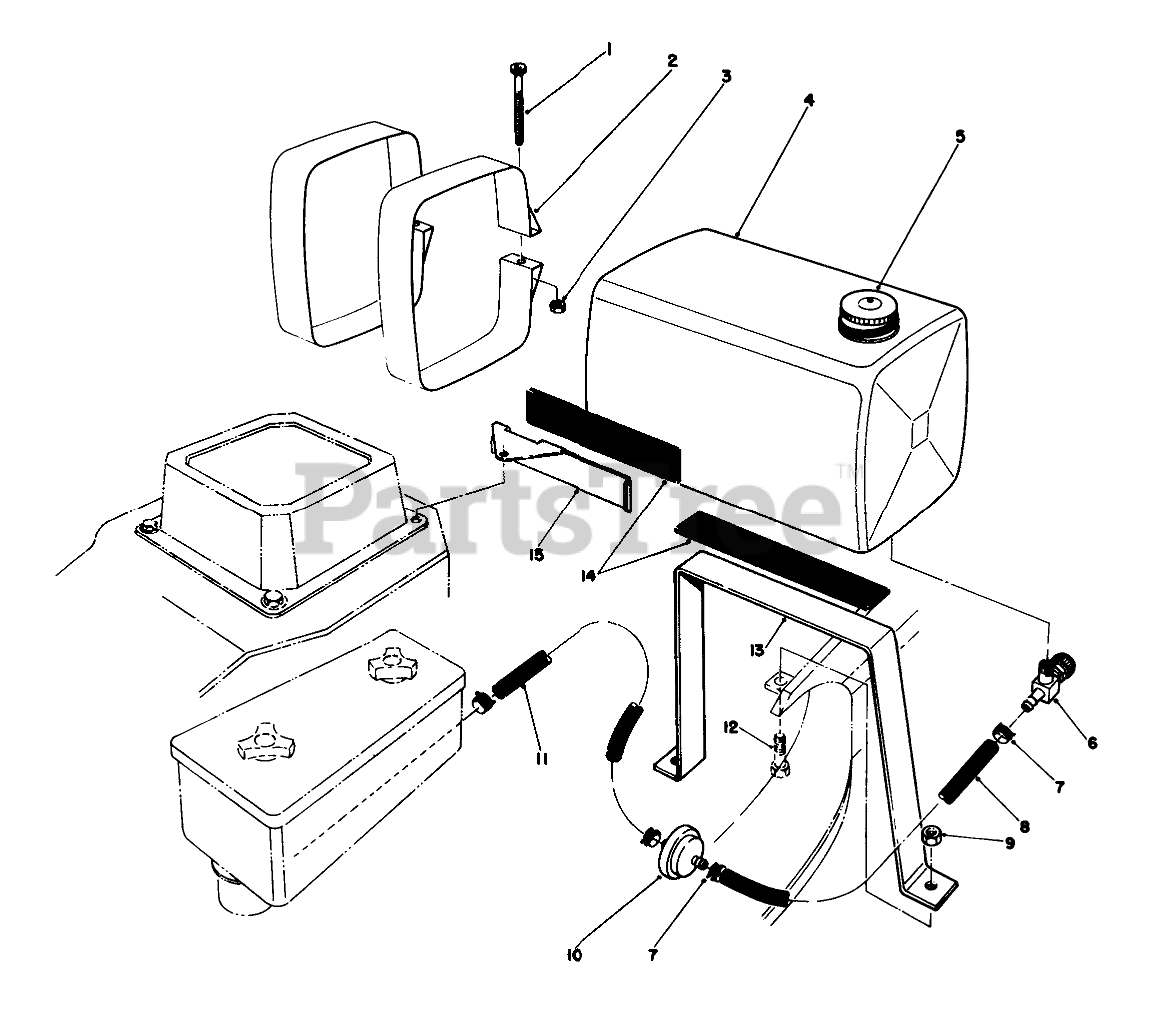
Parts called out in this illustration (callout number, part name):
1	SCREW-HSH
2	TANK MTG STRAP WA
3	NUT-HEX
4	Tank-Gas (Incl. Ref. #5)
5	CAP CAP
6	.125 ID SHUTOFF VALVE
7	CLAMP-FUEL LINE
8	LINE-GAS
9	NUT-LOCK, NI
10	FILTER-FUEL
11	FUEL LINE
12	SCREW-HH
13	TANK SUPPORT
14	ISOLATOR PAD
15	TANK FRAME
